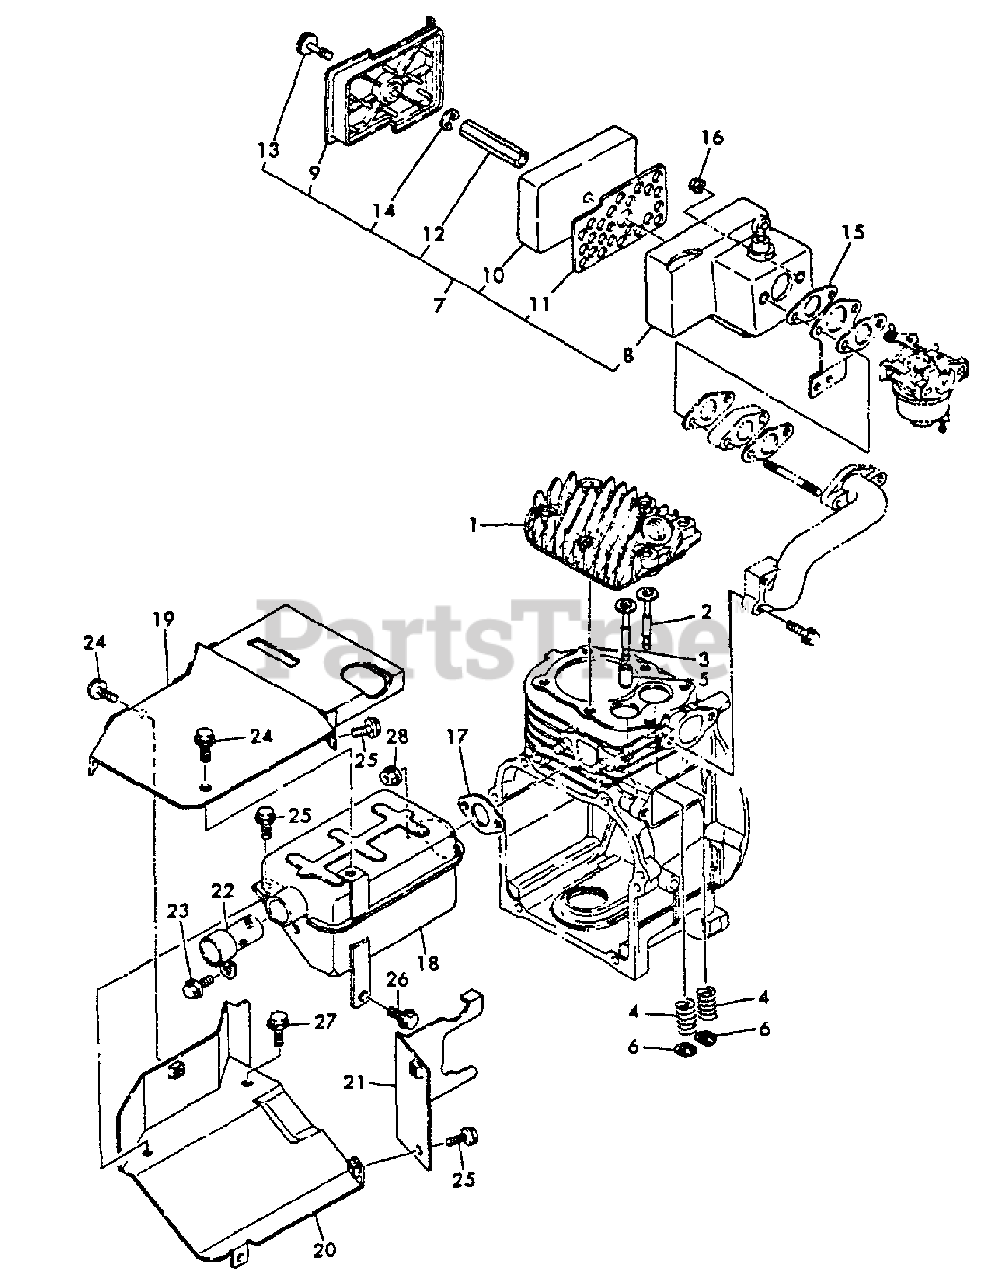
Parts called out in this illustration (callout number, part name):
1	HEAD, CYLINDER
2	VALVE, INTAKE
3	VALVE, EXHAUST
4	SPRING, VALVE
5	GUIDE, VALVE
6	RETAINER, VALVE
7	AIR CLEANER ASSY
8	CASE, AIR FILTER
9	COVER, AIR FILTER
10	FILTER, AIR
11	HOLDER, ELEMENT
12	NUT
14	RING, RETAINING - 5
15	GASKET, INTAKE
16	NUT - 6 -- FLANGE
17	GASKET, EXHAUST
18	MUFFLER
19	GUIDE - A
20	DRIVESHAFT GUIDE ASSY
21	GUIDE C
22	ARRESTOR, SPARK
23	BOLT - 6X8 -- PLATED
24	BOLT - 6X8 -- PLATED
25	BOLT - 6X8 -- PLATED
26	BOLT - 6X12 -- PLATED
27	BOLT - 6X8 -- PLATED
28	NUT - 6 -- FLANGE
